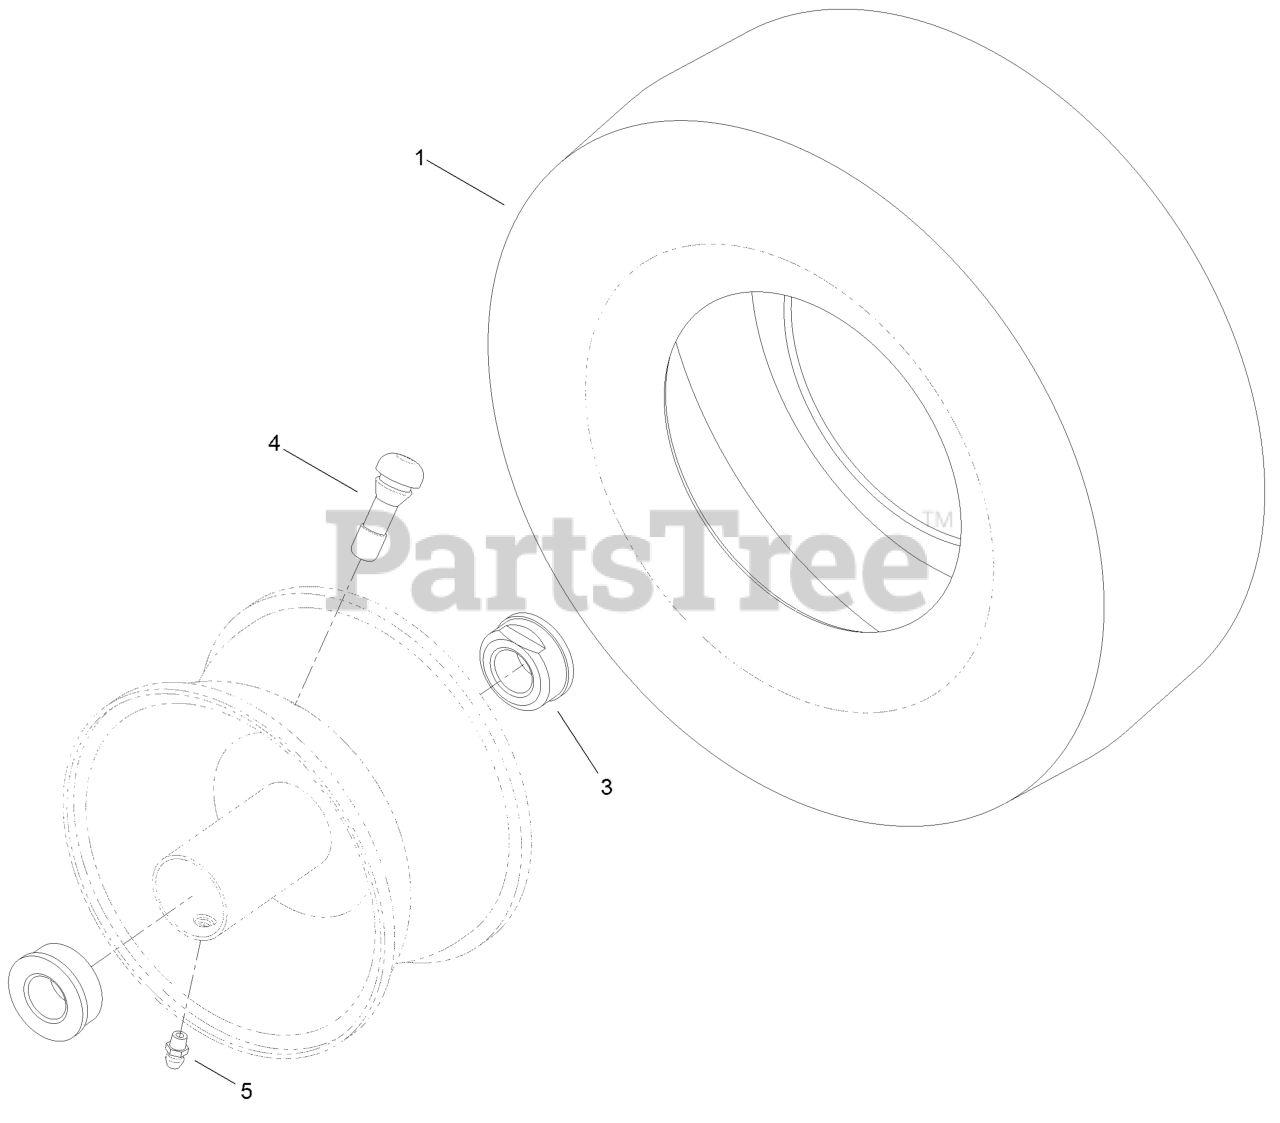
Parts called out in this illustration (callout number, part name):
1	TIRE-13 INCH
3	BUSHING-FLANGE
4	Stem-Valve
5	FITTING-GREASE
